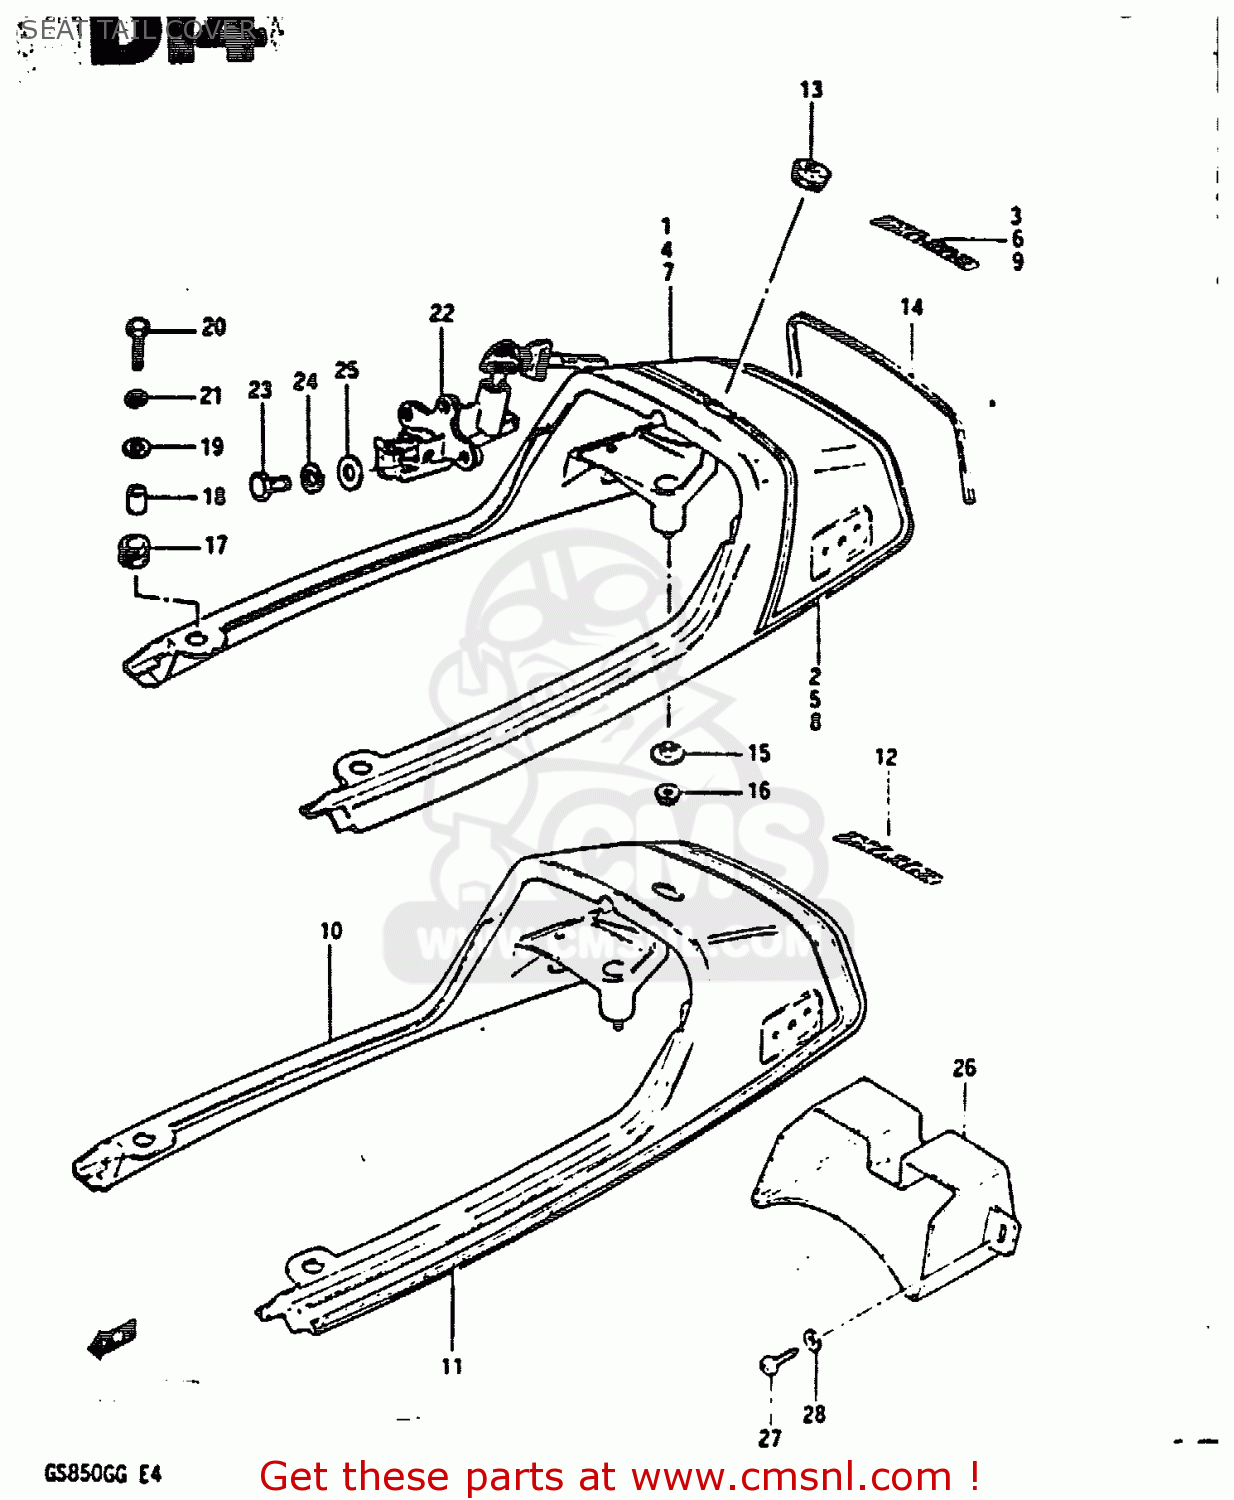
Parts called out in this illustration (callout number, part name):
1	COVER, SEAT TAIL
2	TAPE SET, SEAT TAIL COVER
3	EMBLEM (GOLD)
4	COVER, SEAT TAIL
5	TAPE SET, SEAT TAIL COVER
6	EMBLEM
7	COVER, SEAT TAIL (BLACK)
8	TAPE SET, SEAT TAIL COVER
9	EMBLEM (GOLD)
10	COVER, SEAT TAIL
11	TAPE SET, SEAT TAIL COVER
12	EMBLEM
13	GROMMET,SEAT LOCK HOLE
14	MOLDING,SEAT TAIL COVER
15	WASHER
16	NUT 6MM
17	CUSHION
18	SPACER (7X10X12)
19	WASHER (6.5X24X1.6)
20	BOLT
21	WASHER,LOCK
22	LOCK SET,SEAT
23	BOLT
24	WASHER,LOCK
25	WASHER
26	BOX, SEAT TAIL
27	SCREW 6X12
28	WASHER
